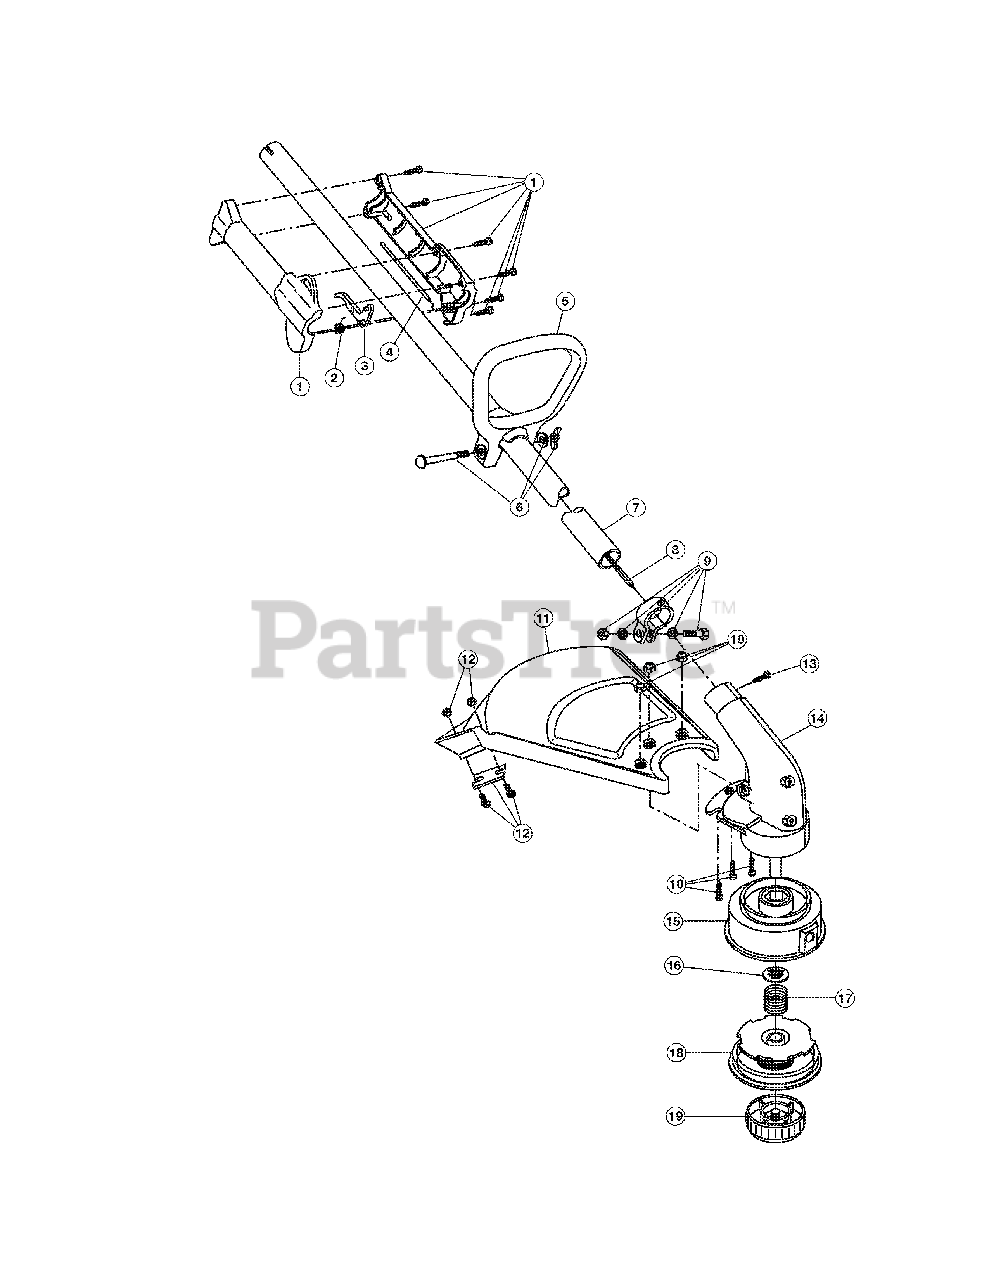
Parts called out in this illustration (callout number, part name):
1	Throttle Housing Assembly (includes 2 & 3)
2	Throttle Trigger Spring
3	Throttle Trigger
4	Throttle Cable
5	D-Handle Assembly (includes 6)
6	D-Handle Hardware
7	Drive Shaft Housing
8	Flexible Drive Shaft
9	Lower Clamp Assembly
10	Guard Mounting Hardware
11	Guard Assembly (includes 12)
12	Blade Assembly
13	Anti-Rotation Screw
14	Gearbox Assembly (includes 15 & 16)
15	Outer Spool Assembly (includes 16)
16	Retainer
18	Inner Reel
19	Bump Head Knob Assembly
